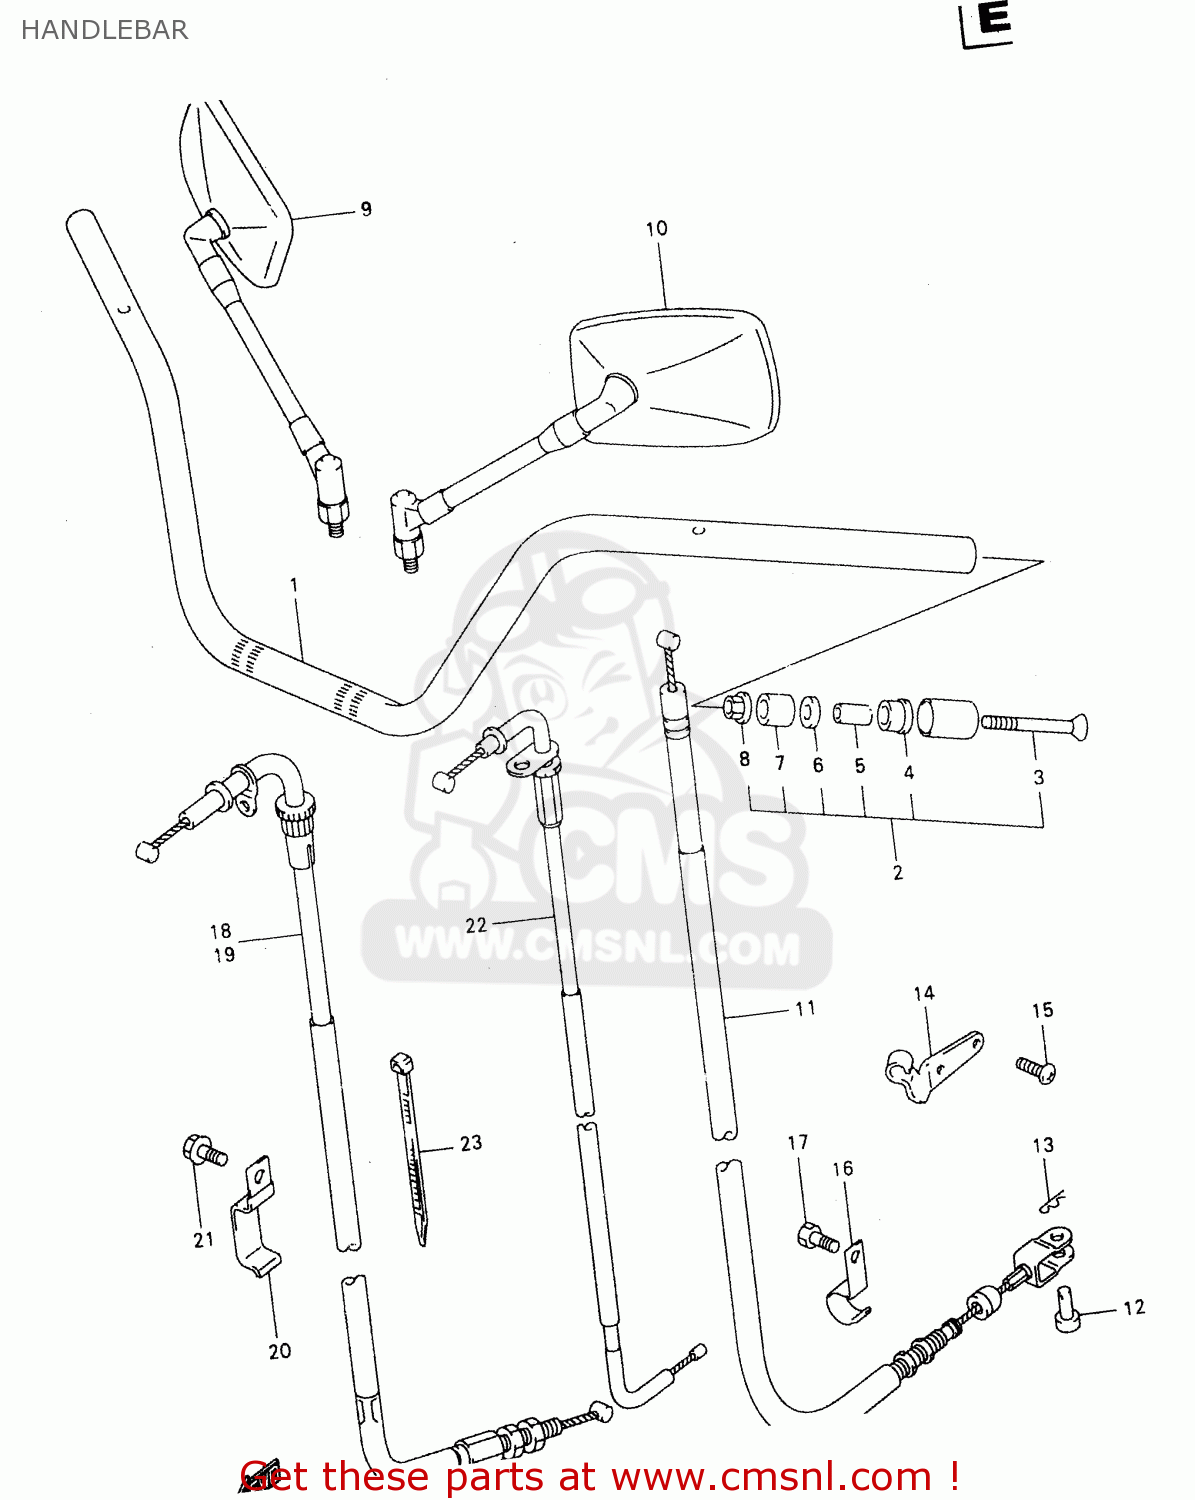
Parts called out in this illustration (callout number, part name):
1	HANDLEBAR
2	BALANCER SET,HANDLEBAR
3	SCREW(6X125)
4	EXPANDER,HANDLE BALANCER NO.2
5	SPACER,EXPANDER
6	WASHER(6.5X14X2)
7	EXPANDER,HANDLE BALANCER
8	NUT
9	MIRROR ASSEMBLY,REAR VIEW
10	MIRROR ASSEMBLY,REAR VIEW
11	CABLE ASSY,CLUTCH
12	PIN(L:13)
13	PIN
14	STOPPER,CLUTCH CABLE
15	SCREW
16	CLAMP,CLUTCH CABLE NO.1
17	SCREW
18	CABLE ASSY,THROTTLE NO.1
19	CABLE ASSY,THROTTLE NO.2
20	CLAMP
21	BOLT
22	CABLE,STARTER
23	CLAMP(L:125)
